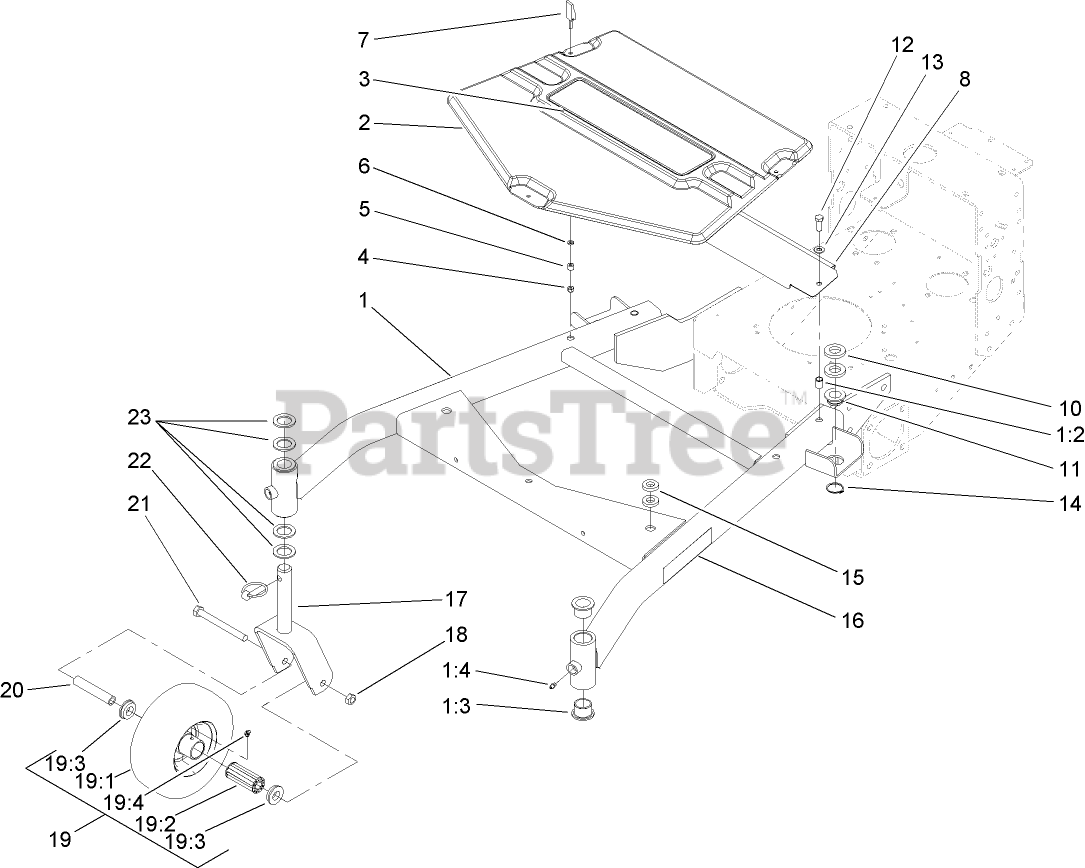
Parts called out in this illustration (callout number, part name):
1	CARRIER FRAME ASM
1:2	INSERT-NUT
1:3	BUSHING
1:4	FITTING-GREASE
2	COVER-FRAME, CARRIER
4	NUT-LOCK, HH
5	BUSHING-LATCH, SWELL
6	WASHER
7	HANDLE-LATCH, SWELL
8	SHIELD-BELT
10	SPACER-SUPPORT, DECK
11	BUSHING-DECK
12	SCREW-HH
13	WASHER-FLAT
14	RING-RETAINING
15	SPACER
16	DECAL-HOC
17	FORK-CASTOR
18	NUT-HEX
19	WHEEL AND TIRE ASM
19:2	BEARING-ROLLER
19:3	BUSHING
19:4	FITTING-GREASE
20	BUSHING-SPANNER
21	SCREW-HH
22	PIN-LYNCH
23	WASHER-THRUST
